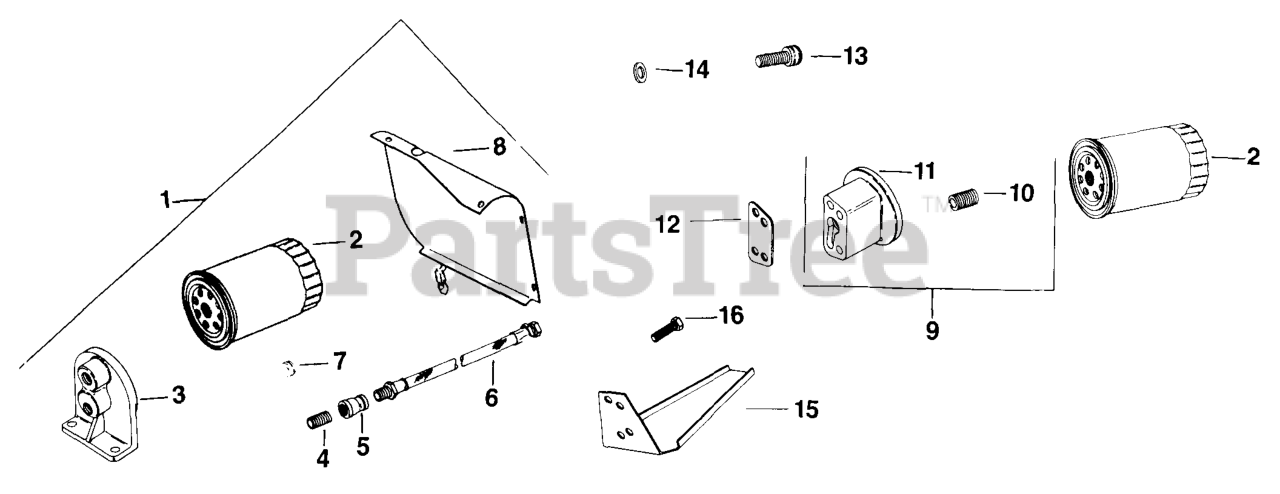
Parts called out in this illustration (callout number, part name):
2	FILTER, OIL
9	ADAPTER
11	ADAPTER - (#DSC)
13	SCREW, HEX SOCKET HEAD CAP USE 25 086 88-S
